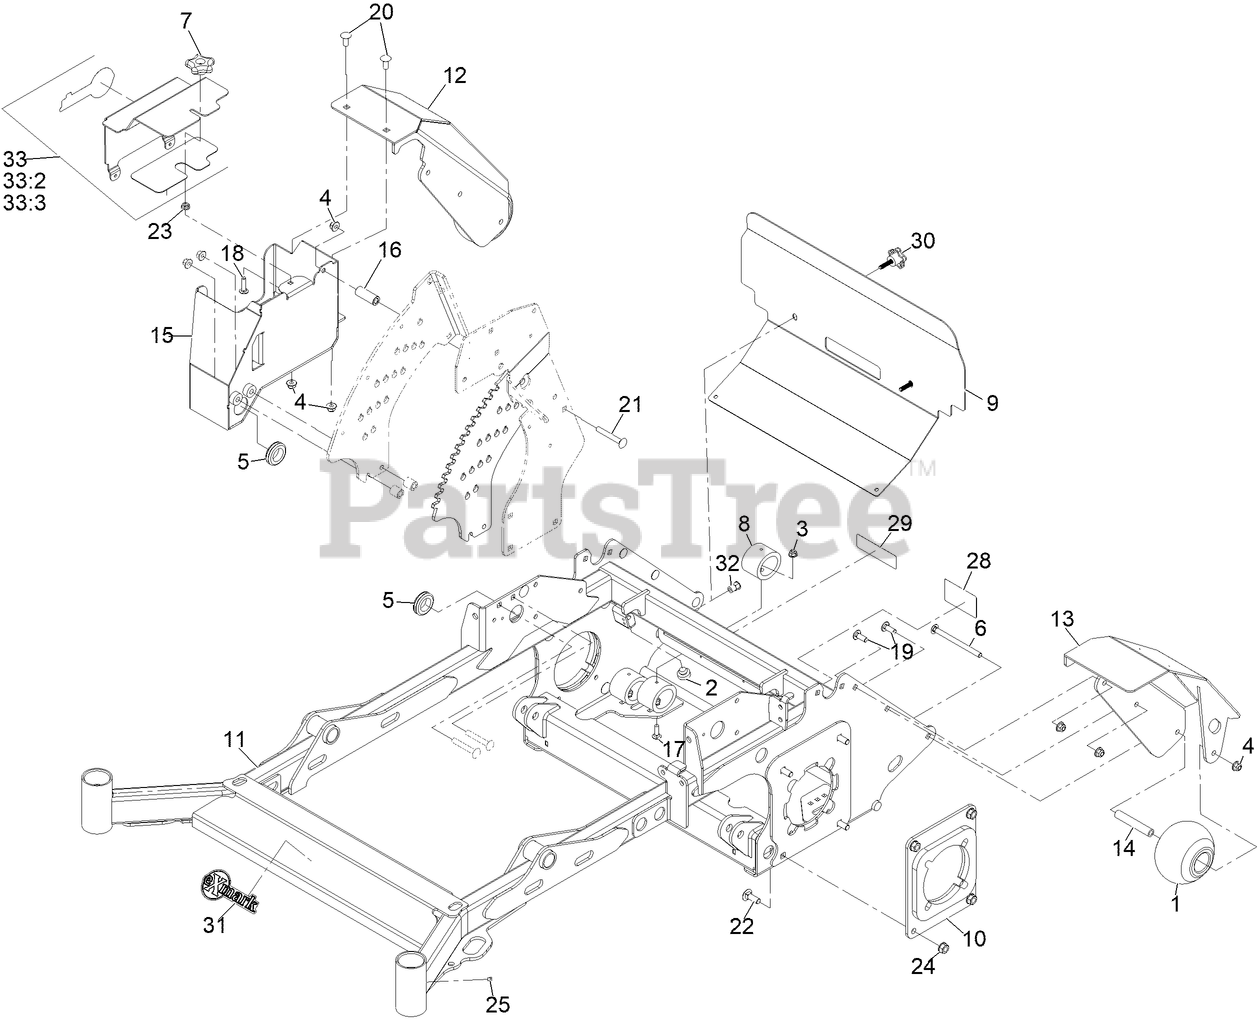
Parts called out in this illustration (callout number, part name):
1	ROLLER-SCALP, ANTI
2	BUMPER-RUBBER
3	NUT-HF, NI
4	NUT-HF, NI
5	GROMMET
6	BOLT-CARR
7	KNOB-HANDLE
8	BUMPER-ISOLATOR
9	GUARD-REAR FOOT
10	WLD-MTR MOUNT 48/52
11	Mainframe ASM -48/52
12	FENDER- WHEEL RH
13	FENDER- WHEEL LH
14	SPACER- ROLLER
15	WELD-BATTERY BOX
16	SPACER- ROLLER
17	BOLT-CARR
18	SCREW-CARR
19	SCREW-CARR
20	SCREW-CARR
21	SCREW-CARR
22	BOLT-CARR
28	DECAL-DRIVE RELEASE
29	DECAL-COVER, MISSING
31	DECAL-EXMARK LOGO
32	NUT-CLINCH
33	ASM-LID BATTERY W/PAD
33:2	PAD-BATTERY BOX LID
33:3	DECAL-EXMARK LOGO
